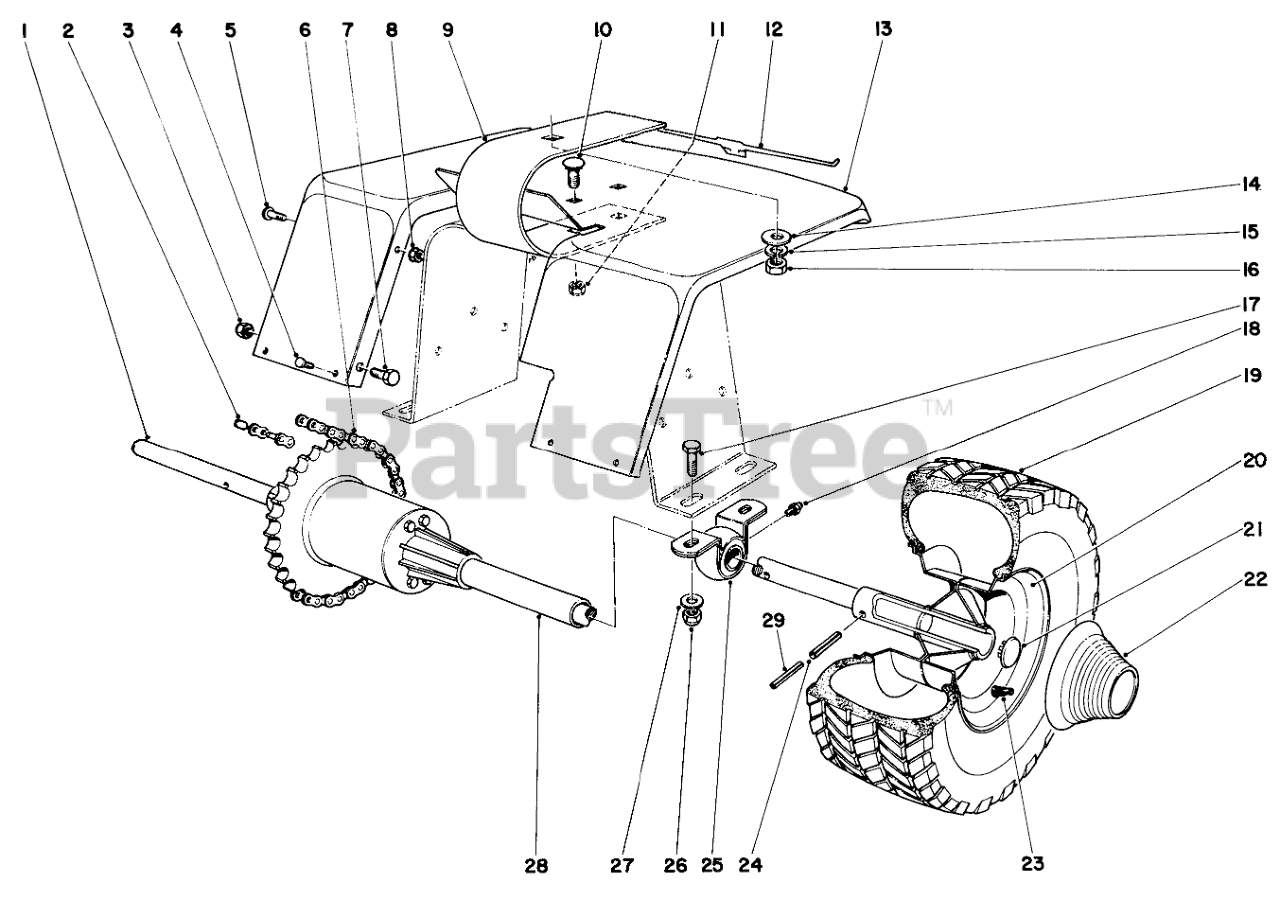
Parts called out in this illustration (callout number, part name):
1	Differential
2	LINK-CONNECTING
3	Nut
4	10-24 X 3/8 PAN HD SC
5	Pan Head Screw
6	Roller Chain
7	SCREW-HH
8	NUT-KEPS
9	Seat Spring
10	BOLT-CARR
12	Decal
13	Fender
14	WASHER-FLAT
15	WASHER-LOCK
16	NUT-JAM
17	SCREW-HH
18	FITTING-GREASE
19	Rear Wheel Assembly 905
21	Button 905
22	Hub Cap Rear
23	Valve Stem
24	PIN-ROLL, SLOTTED
25	PILLOW BLOCK
27	WASHER-FLAT
28	Tube Rear Axle
29	PIN-ROLL
